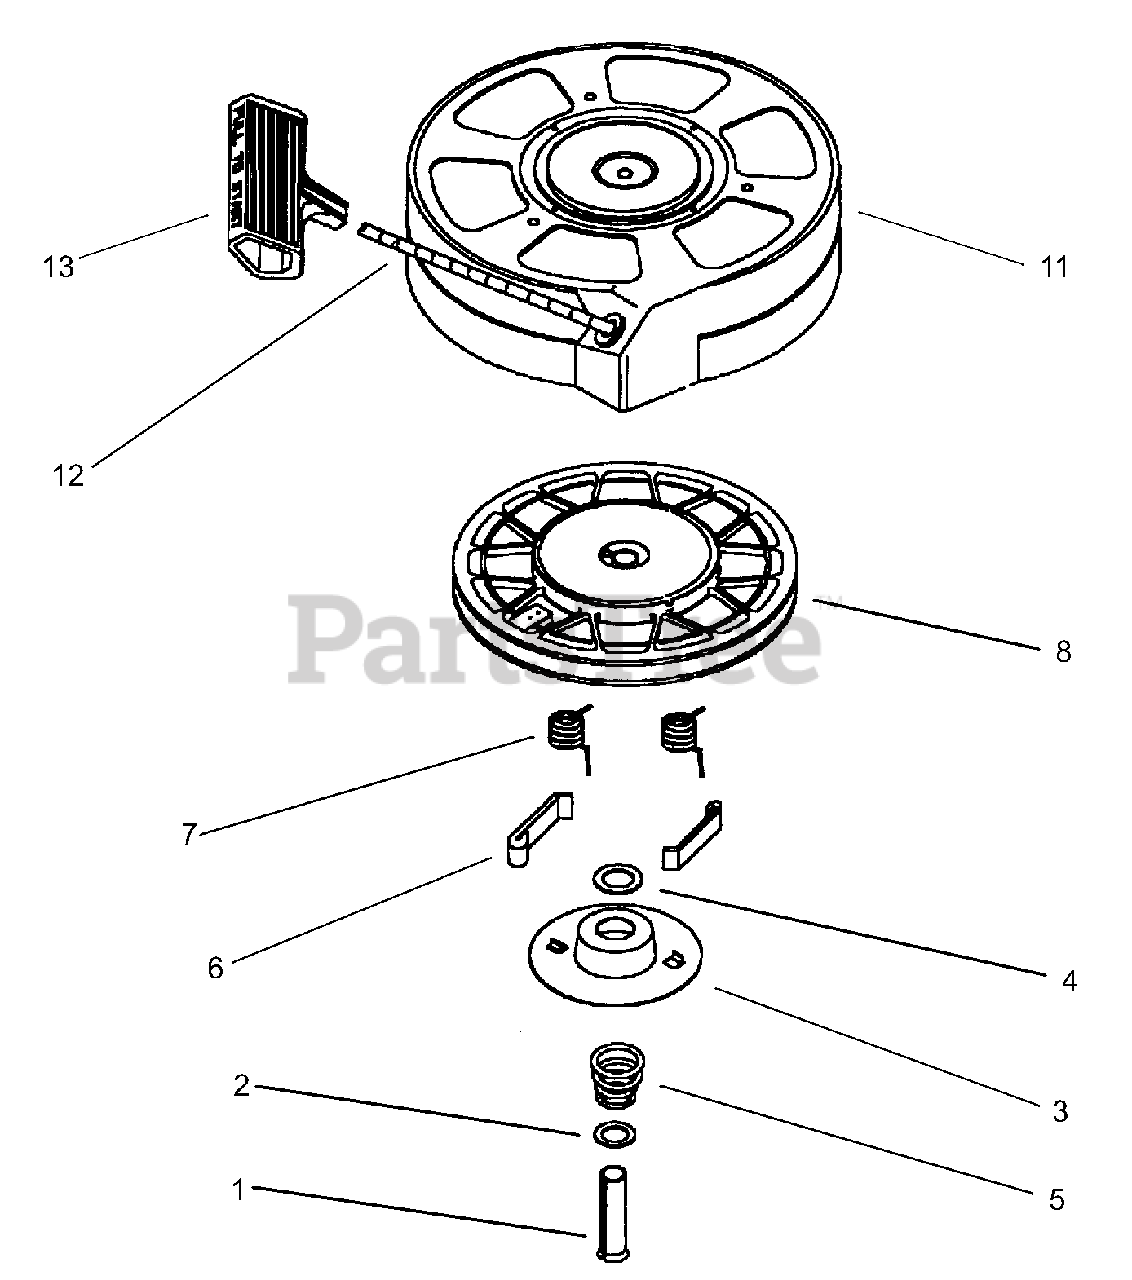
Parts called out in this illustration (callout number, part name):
1	Spring Pin ASM (Incl. Ref. #4)
2	Washer
3	Retainer
4	Washer
5	Spring-Brake
6	Dog-Starter
7	Spring-Dog
8	Pulley and Rewind Spring ASM
11	Starter Housing ASM. (40 degree grommet)
12	Starter Rope ( 98IN X 9/64IN dia.)
13	Handle-Starter
